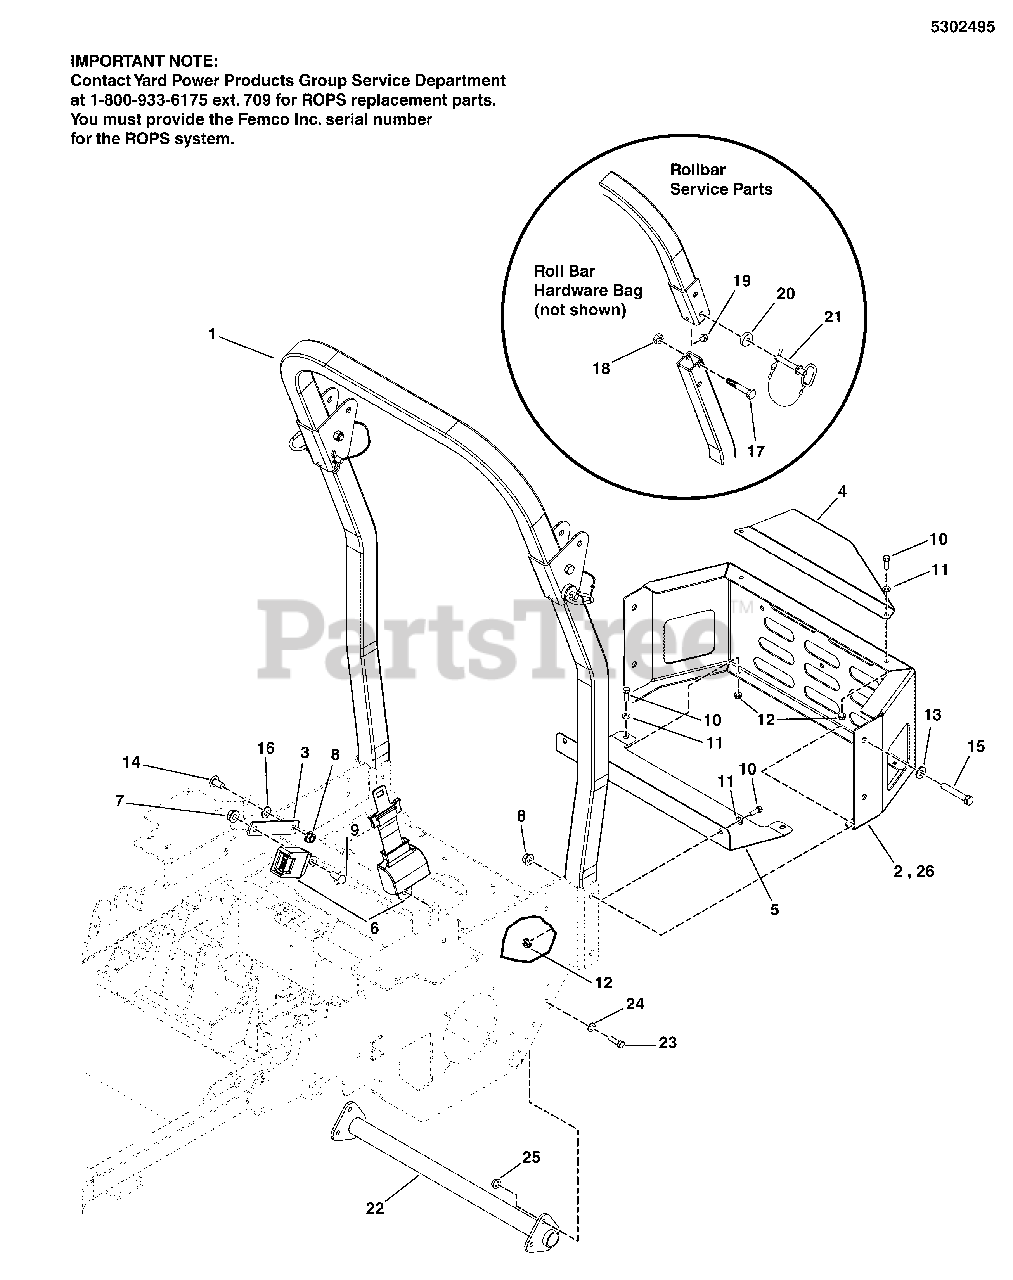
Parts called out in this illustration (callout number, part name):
1	ROPS (Call 1-800-933-6175 ext. 2193 if replacing a ROPS)
2	WELD, PLATE, BUMPER - RED
3	PLATE, SEAT BELT ANCHOR - RH - RED
4	PLATE, CARB. SHIELD - RED
5	PLATE, HEAT SHIELD - BLK
6	SEAT BELT, RETRACTING - ASSM
7	NUT, Hex, Nylon Lock, 1/2-20
8	NUT, Hex Flange, Nylock, 1/2-13
9	SCREW, 1/2-13 X 1.00, SHCS
10	BOLT, 5/16-18 X 3/4 GD5
11	WASHER, 5/16" SAE
12	NUT, 5/16-18 HEX NYLOCK FLANGE
13	WASHER, 1/2 SAE
14	BOLT, 1/2-20 X 1-1/4" GD5 CZ
15	BOLT, 1/2-13 X 3" GD5 CZ
16	WASHER, 1/2 GD9 YZ
17	* BOLT (SV)
18	* NUT (SV)
19	RUBBER BUMPER (SV)
20	RUBBER WASHER (SV)
21	PIN, HITCH, BLACK W/ PLASTIC LANYARD (SV)
22	WELD, BRAKE BUMPER - RED
23	BOLT, 3/8-16 X 1-1/4" GD5 CZ
24	WASHER, 3/8 SAE
25	NUT, 3/8-16 HEX SERRATED FLANGE
26	WELD, PLATE BUMPER - RED
